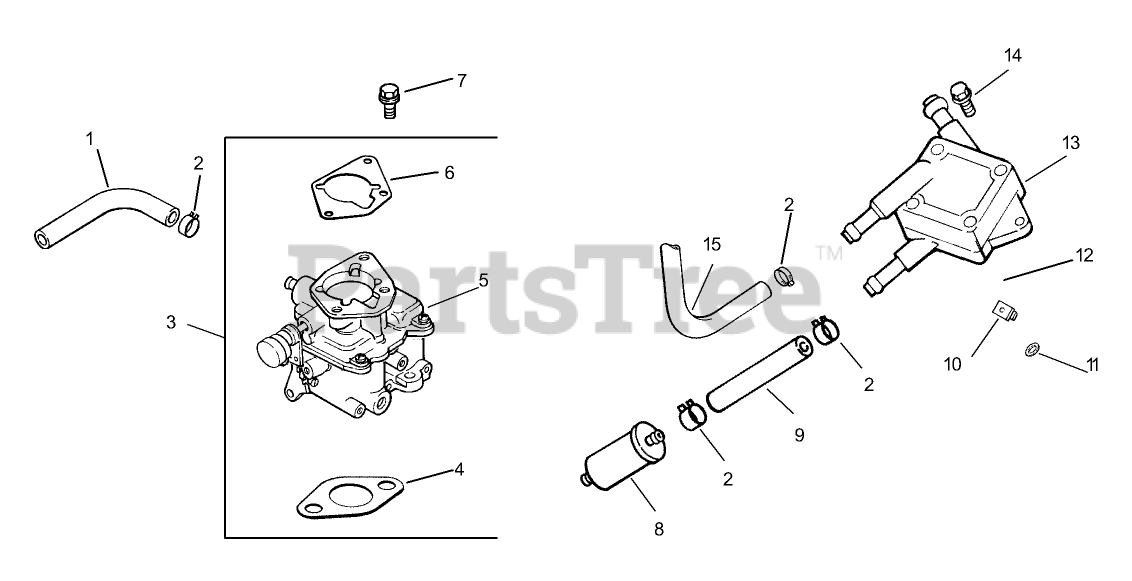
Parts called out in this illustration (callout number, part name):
1	Line-Fuel (9.5)
2	CLAMP-HOSE, SPRING (1/2)
3	Kit-Carburetor w/ Gasket (Incl. Ref. # 4-6)
4	GASKET-BASE, AIR CLEANER
6	Gasket-Carburetor
7	SCREW-FLANGE (M6X1.0X30)
8	Filter-Fuel
9	Line-Fuel
10	Nut-Plastic
10	PUMP-FUEL
11	Spacer
12	Washer-Flat (1/4)
13	PUMP-FUEL
14	Screw
15	Line-Fuel, Flexible (15.5)
